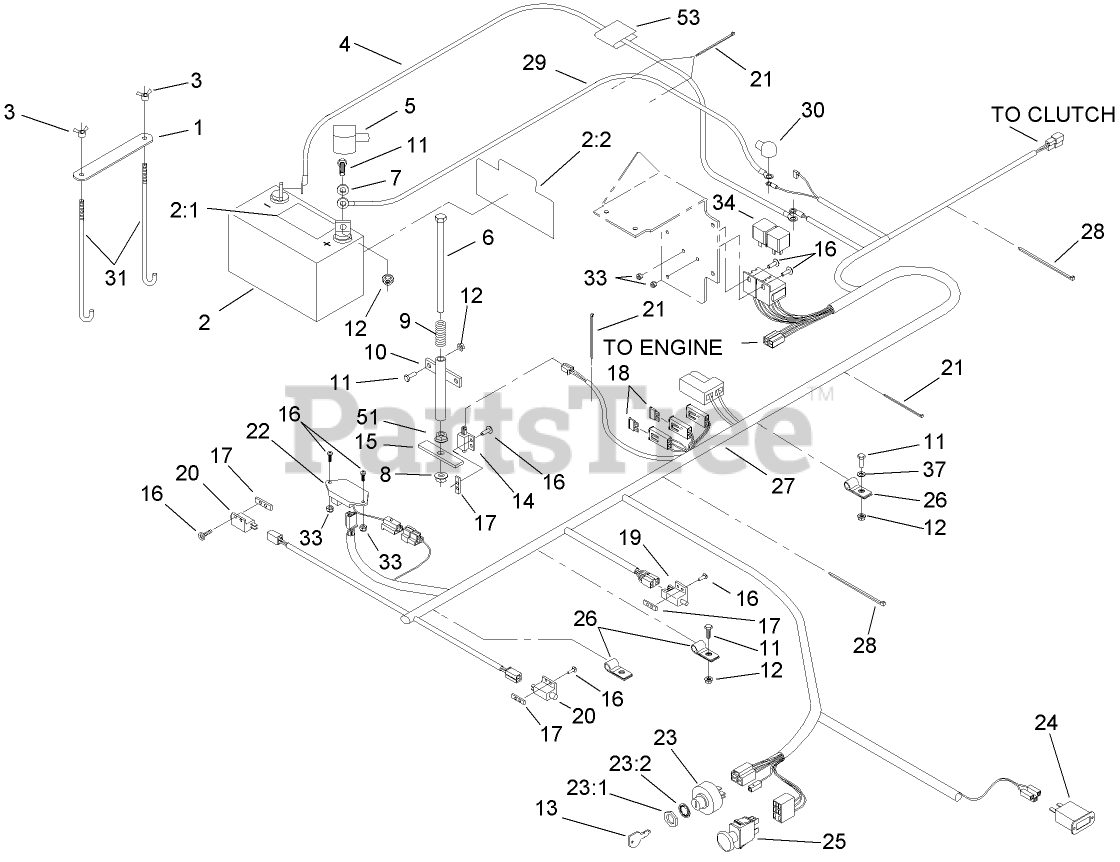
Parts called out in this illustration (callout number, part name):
1	STRAP-HOLDDOWN, BATTERY
2	BATTERY
2:1	Decal-Battery
2:2	Decal-Battery
3	WINGNUT
4	WIRE-GROUND
5	INSULATOR-BATTERY
6	SCREW-HH
7	WASHER-FLAT
8	NUT-LOCK, NI
9	SPRING-SWITCH, SEAT
10	MOUNT-SPRING, SEAT
11	SCREW-HH
12	NUT-HF
13	KEY-IGNITION
14	SWITCH-CLOSED, NORMALLY
15	PLATE-SWITCH, SEAT
16	SCREW-PPH
17	PLATE-TAPPED
18	FUSE-BLADE TYPE, 20 AMP
19	SWITCH
20	SWITCH-OPEN, NORMALLY
21	TIE-CABLE
22	MODULE-DELAY, SEAT
23	SWITCH ASM
23:1	NUT-HH
23:2	WASHER-TOOTH, INTERNAL
24	METER-HOUR
25	SWITCH-PTO
26	CLIP-LOOM
27	Harness-Wire
28	TIE-PLASTIC
29	WIRE-STARTER
30	INSULATOR-SOLENOID
31	BOLT-HOLDDOWN
33	NUT-LOCK, NI
37	WASHER-FLAT
51	NUT-HEX
53	DECAL-INSTRUCTIONS, CHARGING
